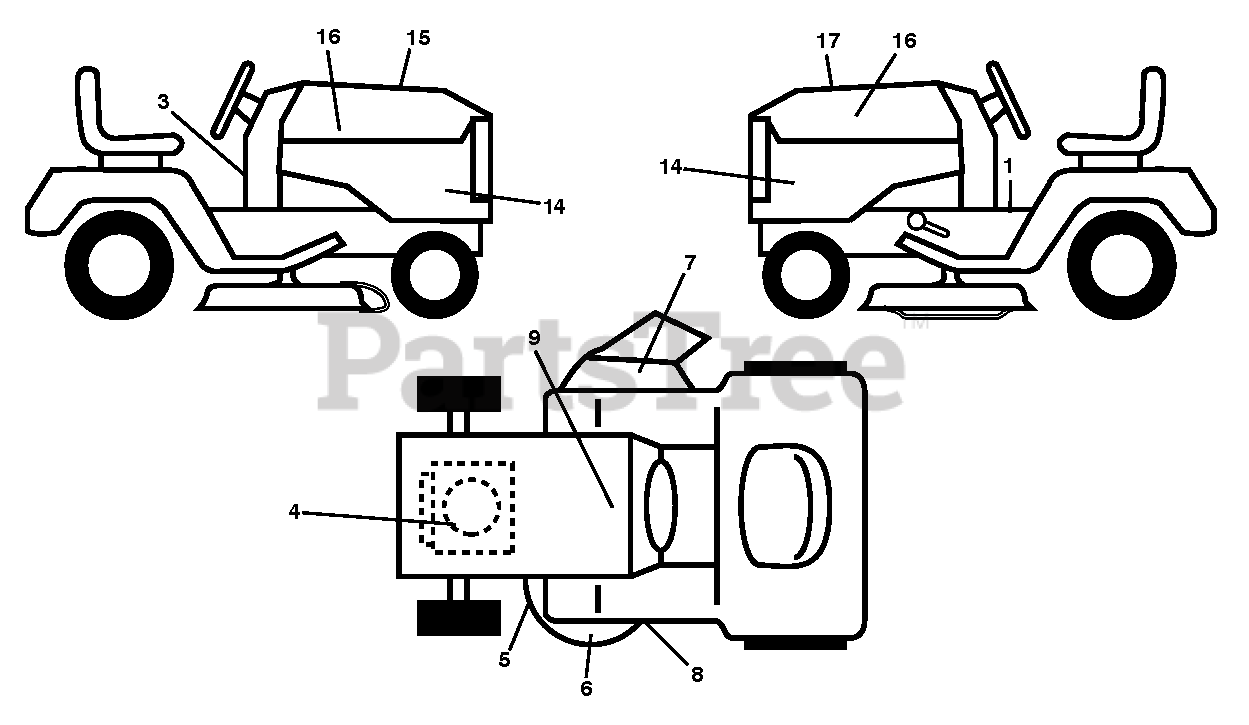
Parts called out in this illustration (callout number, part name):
1	DECAL TRACTOR LOWES DECAL DECA
3	DECAL.SNOWFLAKE.MS498.HUSQ
4	DECAL.ENG.BS.INTK.24HP.382016
5	DECAL.MOWER.CAUTION.TENSION.AR
7	DECAL, DECK DEFLECTOR, WARNING
8	DECAL.MOWER.SCH.48/54.PREM
9	DECAL BTRY SYMBOLS
14	DECAL TRACTOR SIDE PANEL SDPNL
15	DECAL.WARNING.CUST.RESP.E85.
16	DECAL.BADGE.170MM.TEXTLOGO.
17	DECAL.RPL.BSM44INTK.TLW48E.GEN
